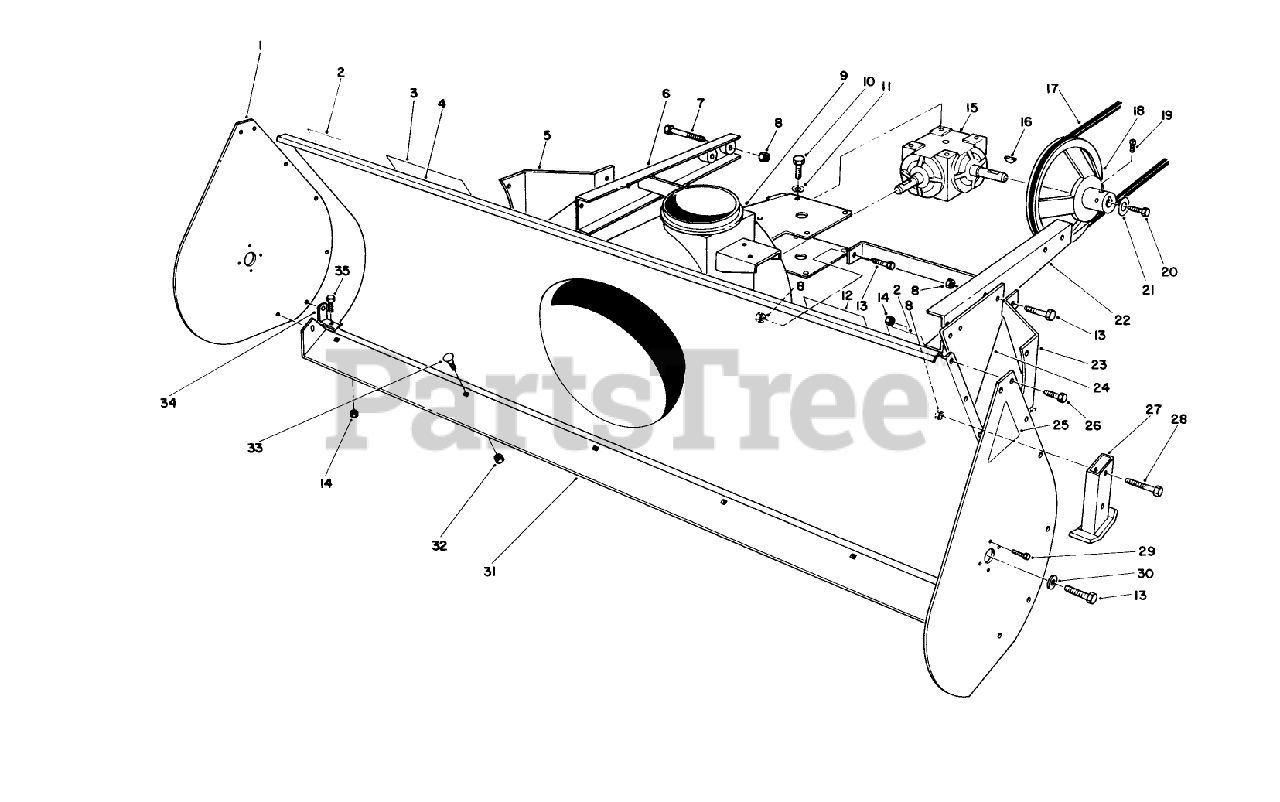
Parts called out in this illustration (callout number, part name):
1	Plate-Side
2	DECAL-WARNING, AUGER
3	Decal-Warning
4	HOUSING WA R
5	RH EXTENSION PLT R
6	RH EXT BAR WA R
7	SCREW-HH
8	NUT-LOCK
9	CHUTE RING
10	SCREW-HH
11	WASHER-LOCK, INTERNAL
12	Decal-Rear Weight
13	SCREW-HH
14	NUT-LOCK, NI
15	GEARBOX
16	KEY-WOODRUFF
17	V-BELT
18	DRIVE PULLEY
19	SCREW-SET, SQH
20	BOLT 60183
21	WASHER-FLAT
22	LH EXT BAR WA R
23	LH EXTENSION PLT R
24	SKID MTG PLT R
25	AUGER SIDE PLT DECAL
26	SCREW-HH
27	SKID WA R
28	SCREW-HH
29	SCREW-HH
30	WASHER
31	Blade-Scraper
32	NUT-LOCK, NI
33	SCREW-CARR
34	BLADE SUPPORT BRKT R
35	SCREW-HH
